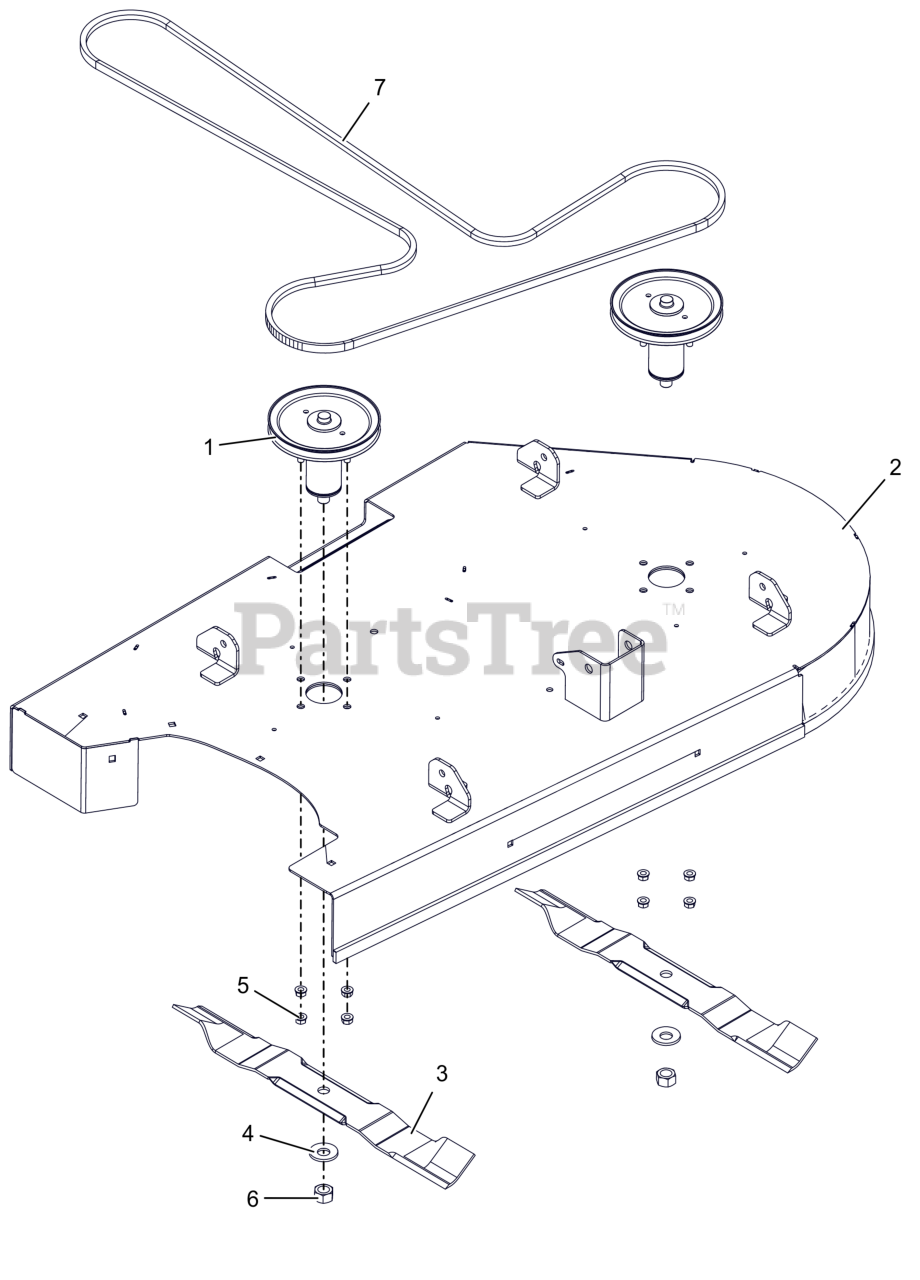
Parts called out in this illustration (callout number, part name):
1	KIT- DECK SPINDLE ASSM
2	KIT- 42" EDGE DECK W/DECALS
3	BLADE, 21" 35 DEG
4	WSHR-BLVL .669X1.535X.138
5	NUT,LK-CTR-FLG .31-18 GF ZCC
6	NUT-STD .625-18 ZCC
7	V-BELT, HA-WRAPPED
